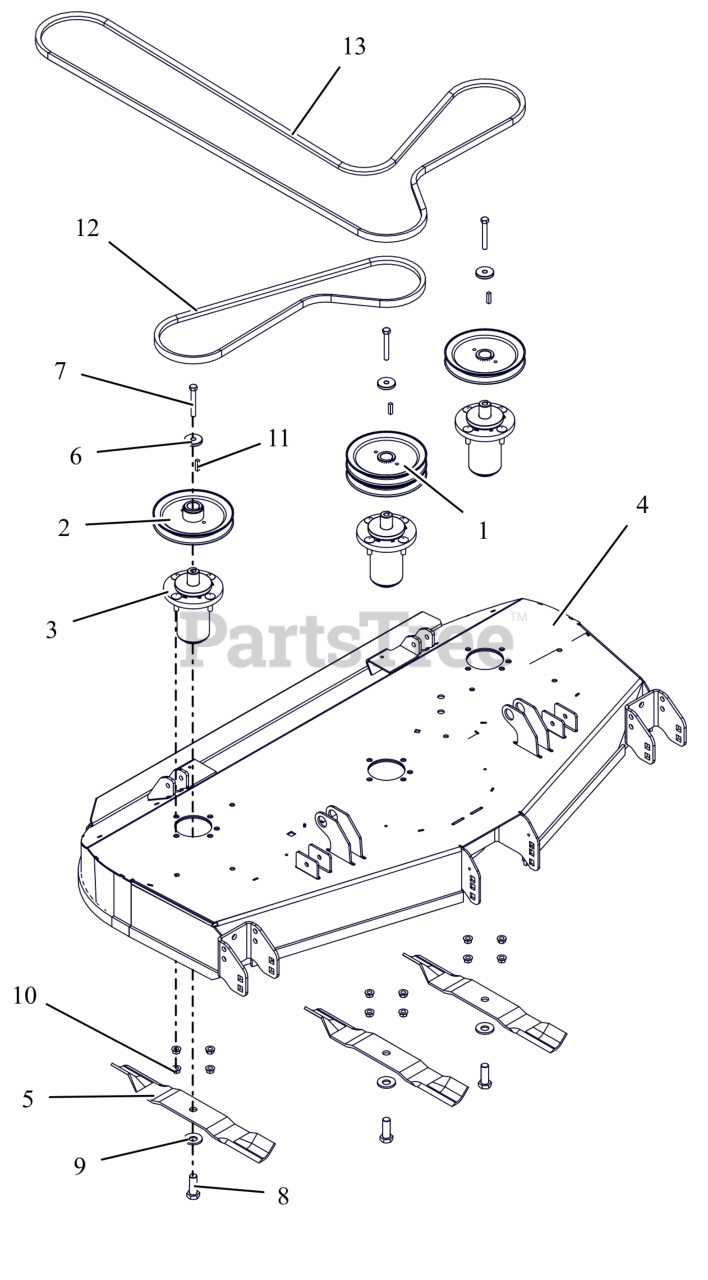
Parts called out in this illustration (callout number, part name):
1	PULLEY, DOUBLE 1.000 ID X 6.750 OD-BLACK
2	PULLEY, V-1.000 ID X 6.750 OD
3	ASM, MAINT FREE ALUM SPINDLE
4	WLDMT- 52" RD DECK
5	BLADE, 18"
6	RETAINER, SHEAVE
7	BLT, HEX .38-16X2.75 G8 ZCC
8	BLT, HEX .62-18X1.75 G8 ZCC
9	WSHR-BLVL .669X1.535X.138
10	NUT-LK-CTR-FLG .375-16 GF ZCC
11	KEY, SQ .25X.25X1.00 RC 40-50
12	V-BELT, B-COGGED
13	V-BELT, HB SECTION
